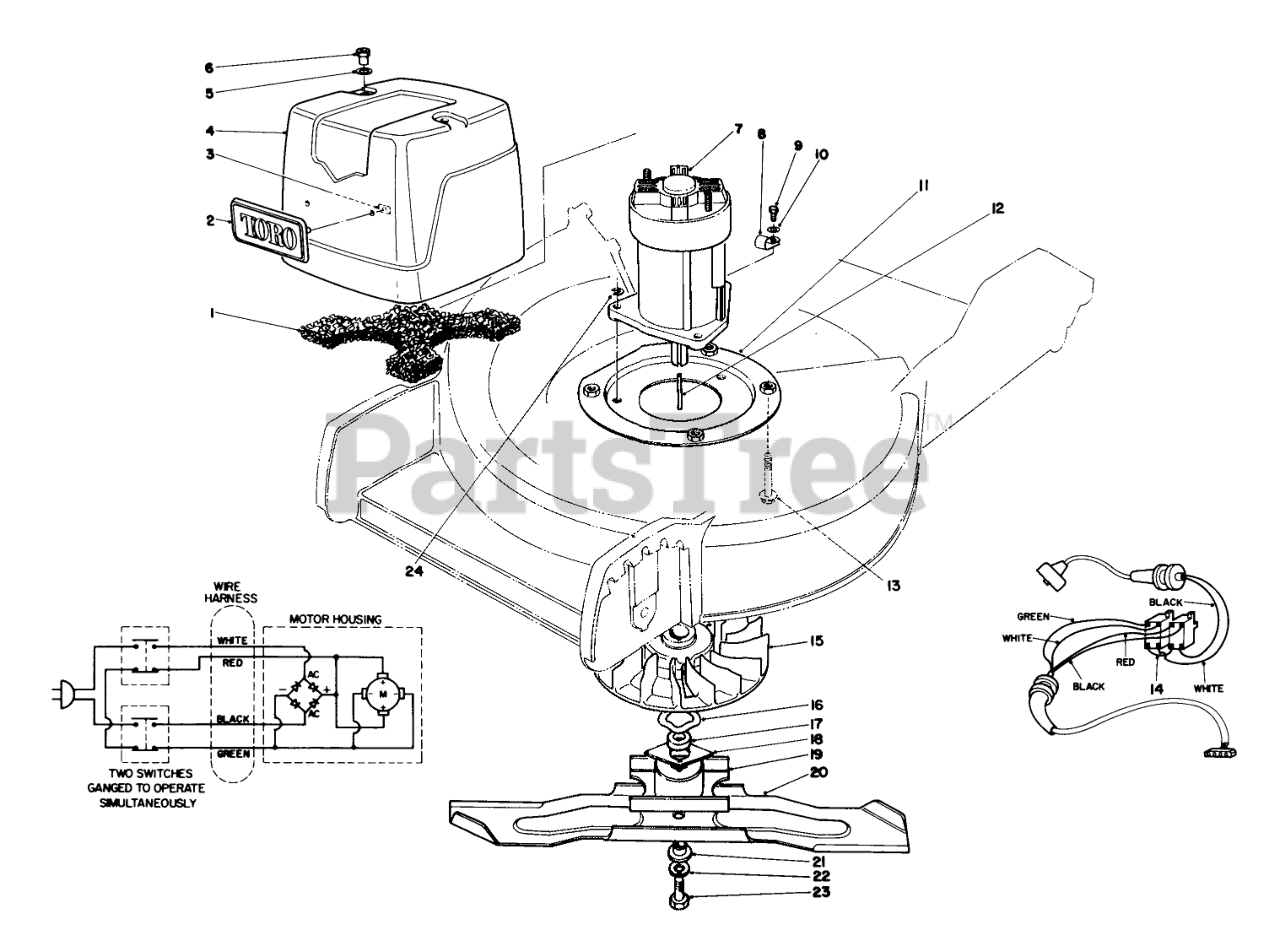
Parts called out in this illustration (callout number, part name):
1	FILTER F/W
2	TORO LOGO PLT
3	Receiver-Stud
4	Shroud-Motor
5	WASHER F/W
6	NUT F/W
7	Motor-Electric
8	CLAMP
9	SCREW-HH
10	WASHER-FLAT
11	MOTOR MOUNT ASM WA
12	KEY-SQUARE
13	SCREW-HHF
14	BRAKE WIRE
15	FAN F/W
16	WAVE WASHER
17	BLADE RETAINER SPACER
18	FAN DRIVER
19	BLADE RETAINER WA
20	Blade
21	BLADE SPACER
22	WASHER-LOCK/SP
23	SCREW-HH
24	WASHER-LOCK/EXT
